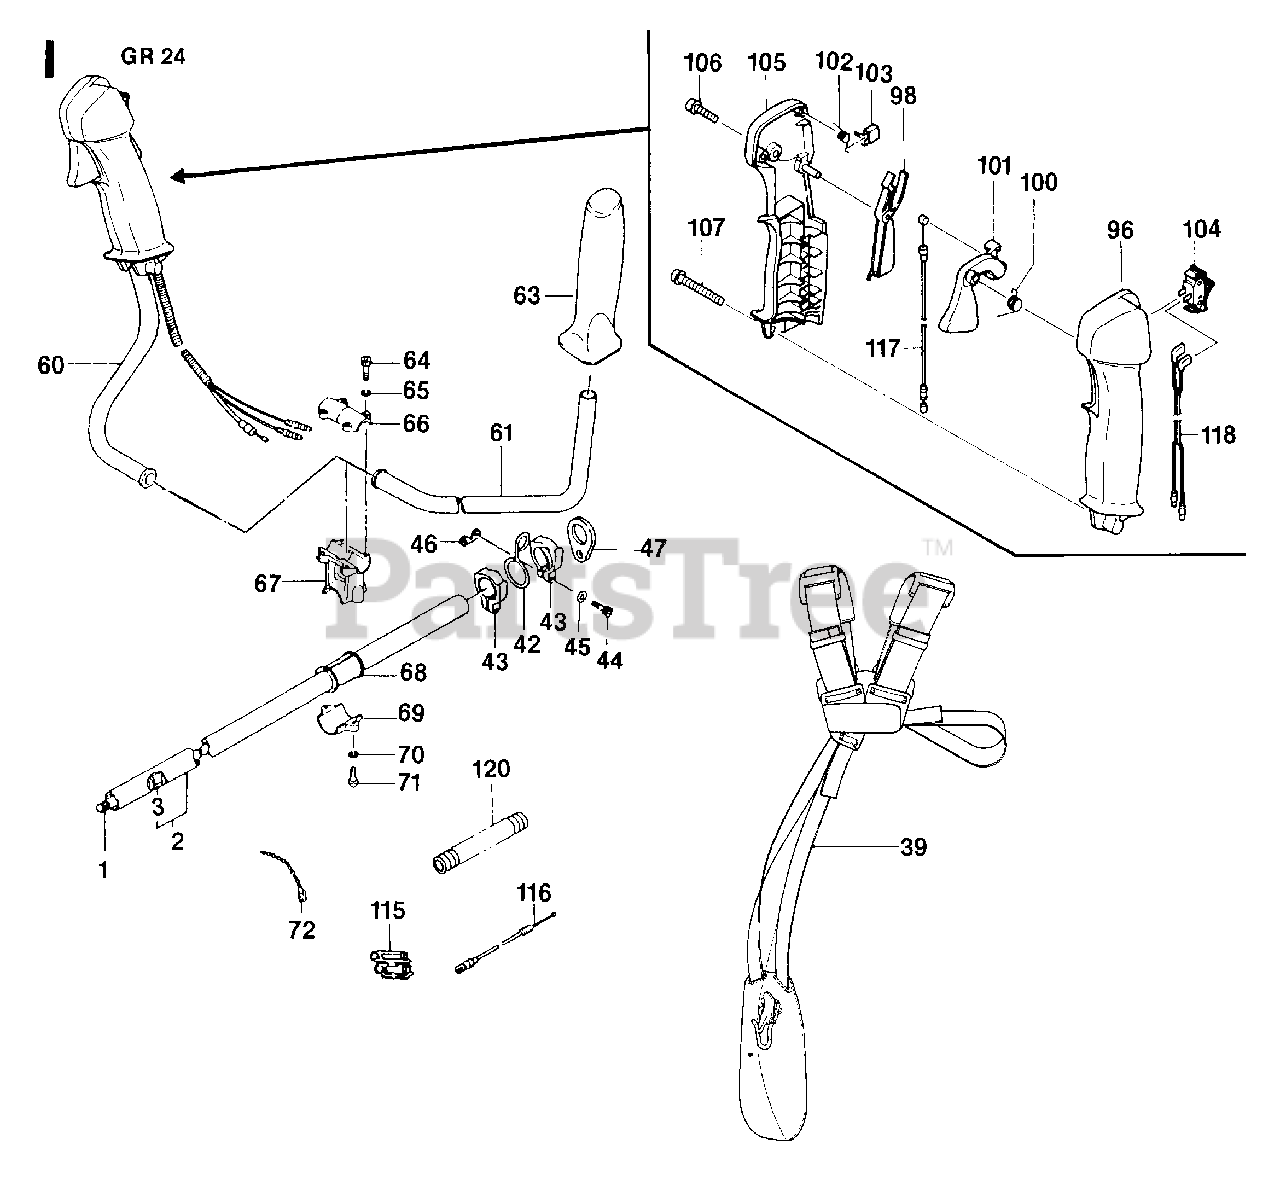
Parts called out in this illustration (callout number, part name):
44	SCREW MC6S 5X30
45	WASHER 5.3X12
64	SCREW MC6S 5X25
65	SPRING WASHER
70	SPRING WASHER
98	THROTTLE LOCKOUT
100	SPRING
101	THROTTLE TRIGGER
102	TRIGGER SPRING
103	THROTTLE LOCK
104	SWITCH
